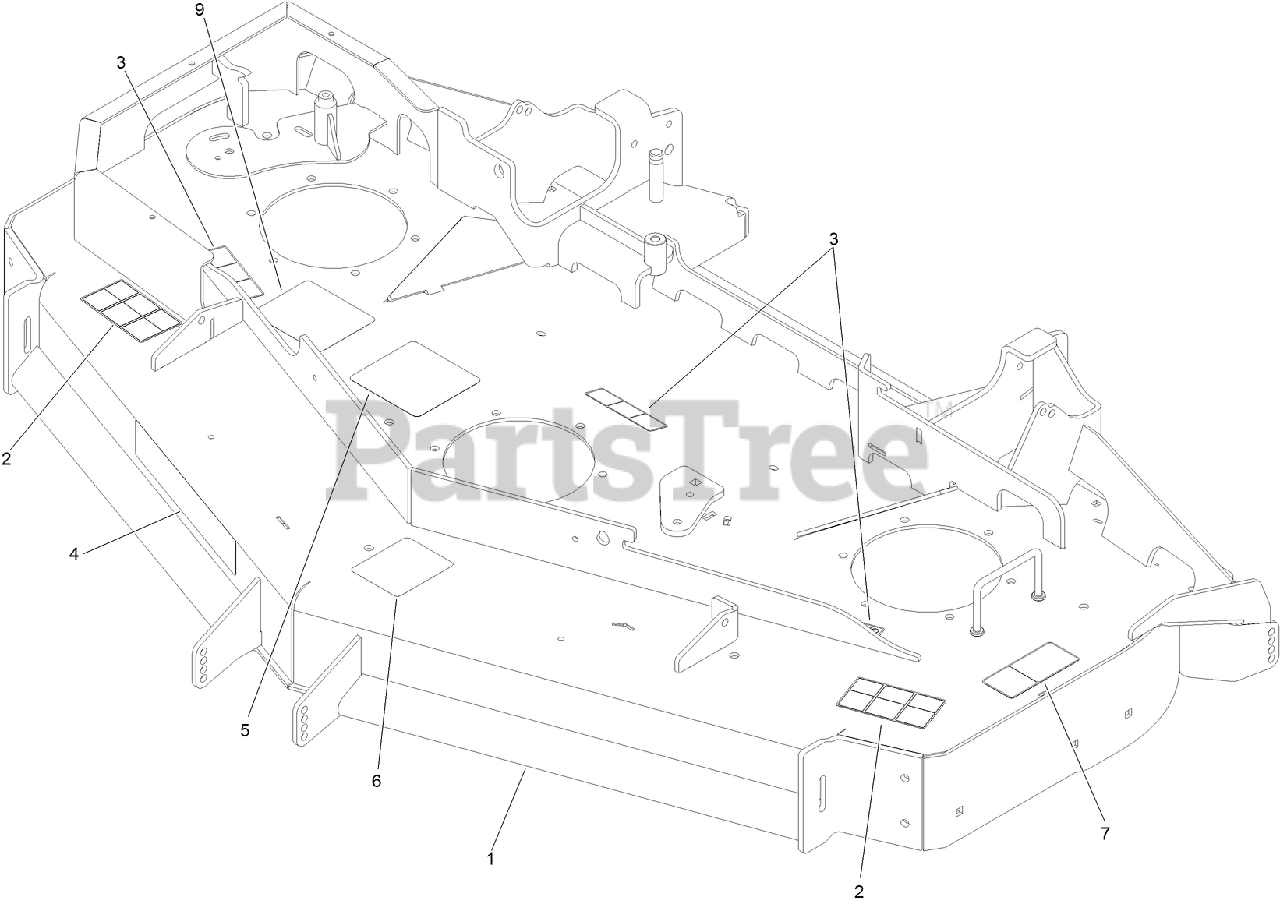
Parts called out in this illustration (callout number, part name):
1	DECK DECAL ASM
2	DECAL-DANGER
3	DECAL-COVER, MISSING
5	DECAL-ROUTING, DECK BELT
6	DECAL-ROLLER, ANTI-SCALP
7	DECAL-TORQUE, BLADE BOLT
9	DECAL-SPINDLE, COUNTER ROTATING
